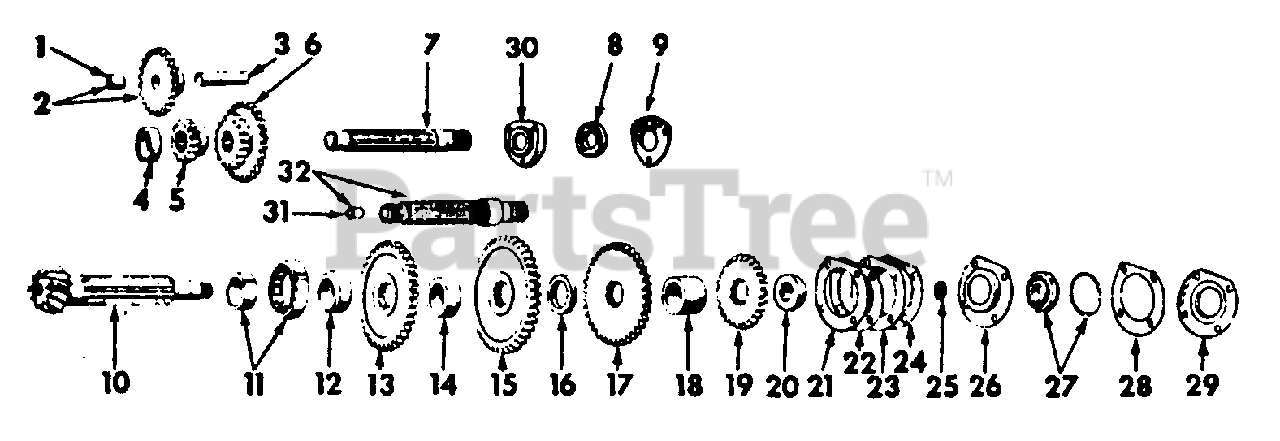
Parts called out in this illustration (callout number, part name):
1	Bushing, Reverse Idler Gear
2	Gear w/Bushing, Reverse Idler -22T
3	Shaft, Reverse Idler
4	Bearing Assy, Transmission Main Shaft Rear Needle
5	Gear, First and Reverse Speed Sliding -13T
6	Gear, Second and Third Speed Sliding -17T and -26T
7	Shaft, Transmission Main
8	Bearing Assy, Transmission Main Shaft Front Ball
9	Retainer, Transmission Main Shaft Front Bearing
10	Countershaft and Bevel Pinion Nut, 3/4-16 Hex, Jam
11	Bearing Assy, Countershaft Rear Roller
12	Spacer, Reverse Speed Gear and Countershaft Bearing
13	Gear, Reverse Speed -35T
14	Spacer, First and Reverse Speed Gear
15	Gear, First Speed -39T
16	Spacer, First and Second Speed Gear
17	Gear, Second Speed -35T
18	Spacer, Second and Third Speed Gear
19	Gear, Third Speed -26T
20	Spacer, Third Speed Gear and Countershaft Bearing
21	Shim, Countershaft Brg Retainer, .004
22	Shim, Countershaft Brg Retainer, .007
23	Shim, Countershaft Brg Retainer, .0149
24	Shim, Countershaft Brg Retainer, .0299
25	Nut, 3/4-16 Hex Jam
26	Retainer, Countershaft Brg
27	Bearing Assy, Countershaft Front Ball
28	Gasket, Countershaft Brg Retainer
29	Retainer, Countershaft Brg
30	Cage, Transmission Main Shaft Front Brg
31	Bushing, PTO Shaft Pilot
32	Shaft Assy, Transmission Input
